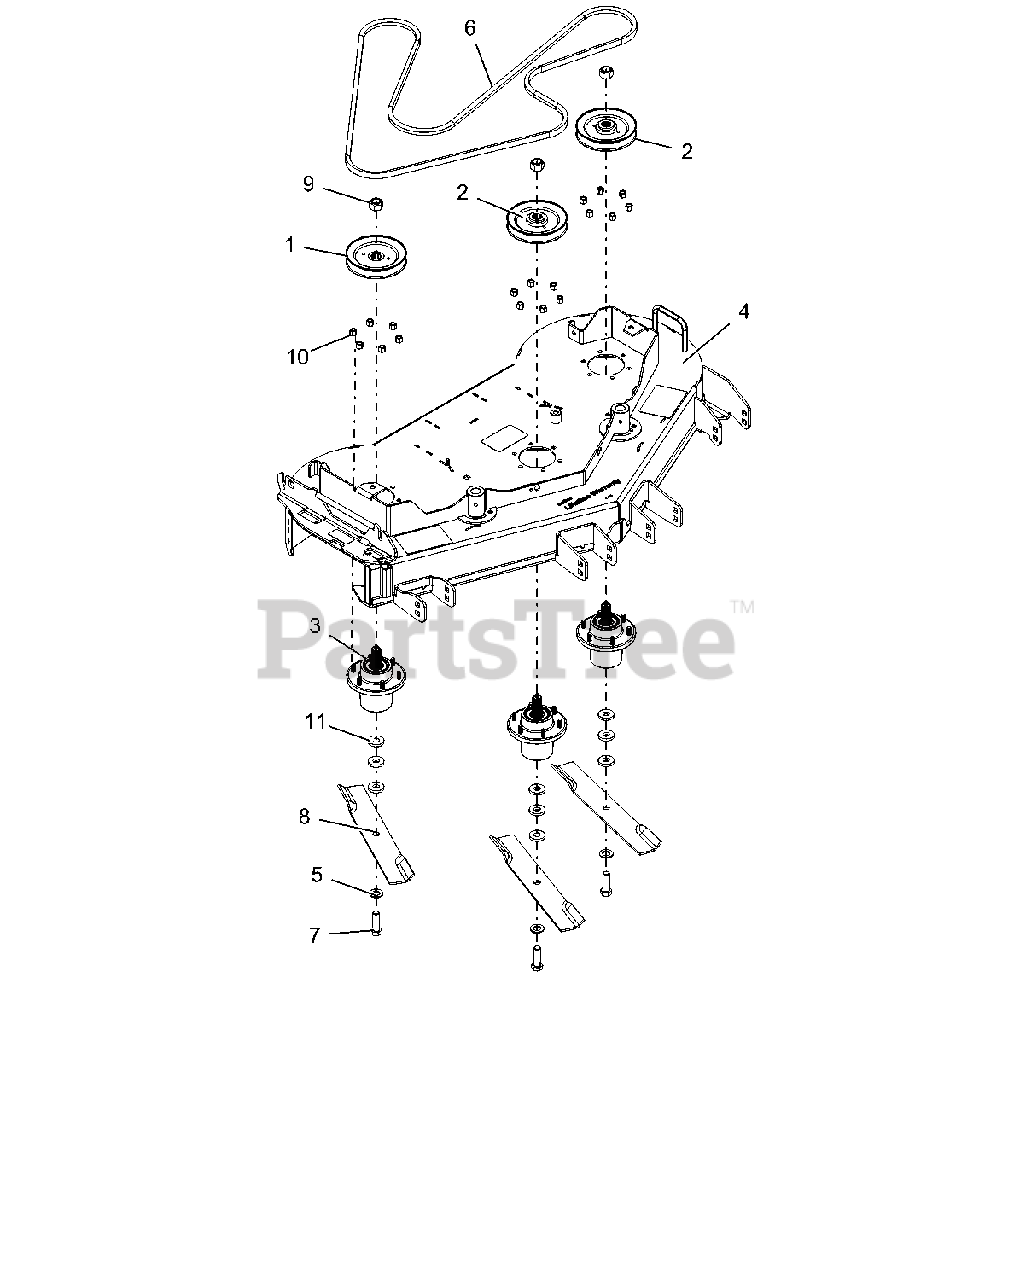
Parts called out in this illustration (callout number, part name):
1	PULLEY, SPINDLE 5.75 X .76-BLACK
2	PULLEY, SPINDLE 5.75 X .25-BLACK
3	ASSY, SPINDLE HOUSING
4	ASSY, 48 FLWLKDECK W/DECALS
5	WASHER, .75X1.3125X.120
6	BELT, HB
7	BLT-HEX .62-11X2.00 GR8 YWZC
8	BLADE, 16.50 LO-LIFT
9	LOCKNUT, 3/4-16 CROWN GR5 Y
10	NUT-LK-NYL .38-16 YWZC
11	WSHR-FL-STL .630X1.50X.25 YWZC
